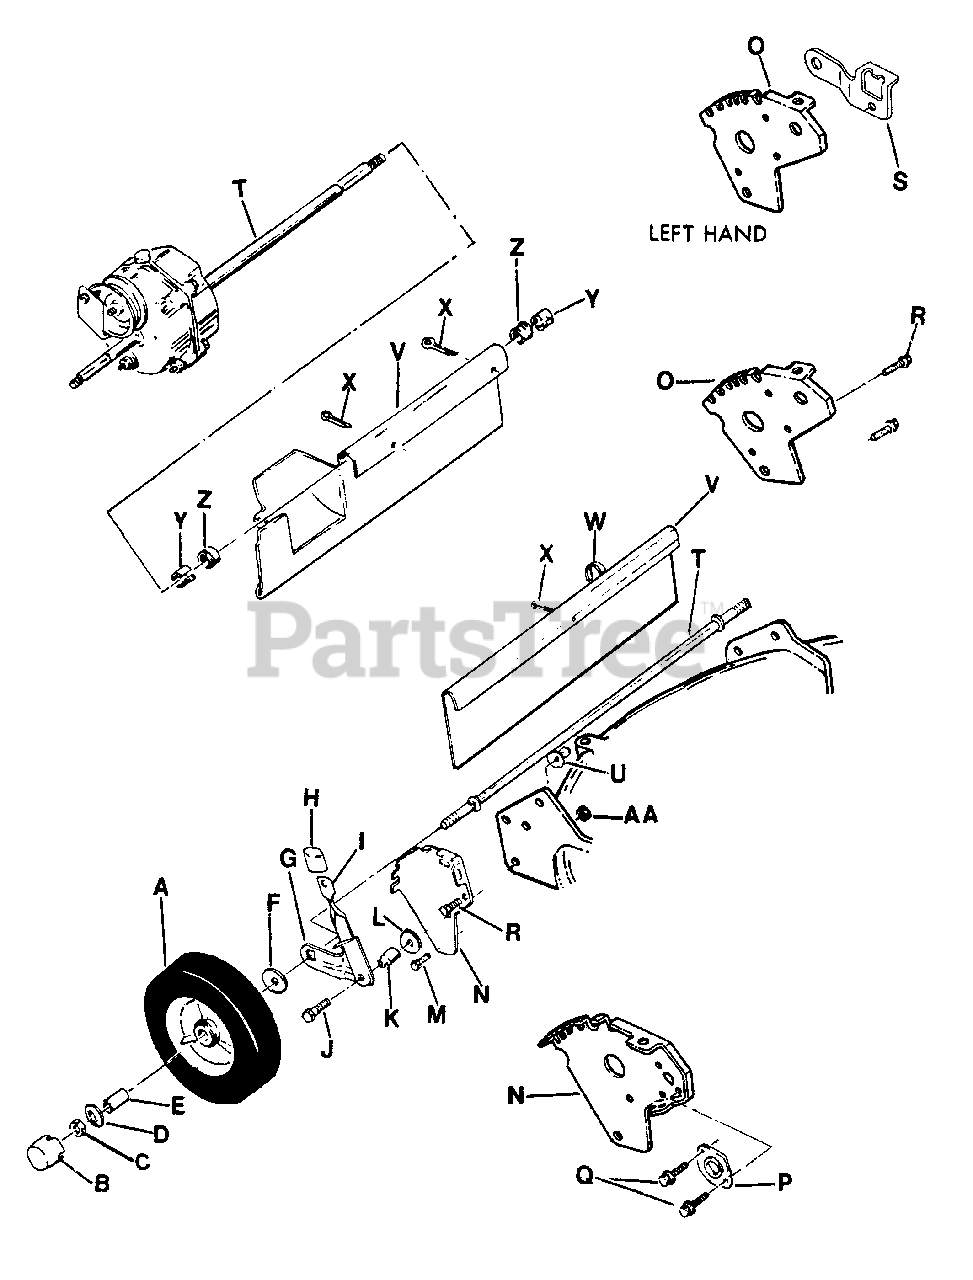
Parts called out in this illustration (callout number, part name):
A	WHEEL, V18 Rear-7 x 1.50 (9/16" Internal Diameter)
B	CAP, Hub
C	NUT, 7/16-20 Hex Center Lock (Thin)
D	WASHER, Spring
E	BUSHING, Axle
F	WASHER, 7/16" Steel
G	ARM, RH Rear Wheel
H	GRIP, Height Latch
I	LATCH, Rear Height
J	SCREW, 5/16-18 x 1" Shoulder
K	SPACER, Wheel Arm
L	RETAINER, 5/16" Bolt
M	SCREW, 5/16-18 x 5/8" Hex Washer Self-Tap
N	BRACKET, RH Rear
O	BRACKET, LH Rear
P	HOLDER, Bearing
Q	SCREW, 1/4-20 x 3/8" Hex Washer Self-Tap
R	SCREW, 5/16-18 x 3/4" Hex Washer Self-Tap
S	ARM, LH Rear Wheel
T	AXLE, Rear
U	NUT, 5/16-18 Tee
V	GUARD, Foot Rear
W	RING, Nylon
X	PIN, 1/8 x 1-1/2" Cotter
Y	SPACER, Axle
Z	BUSHING, Axle (Nylon)
AA	NUT, 5/16-18 Hex Jam
